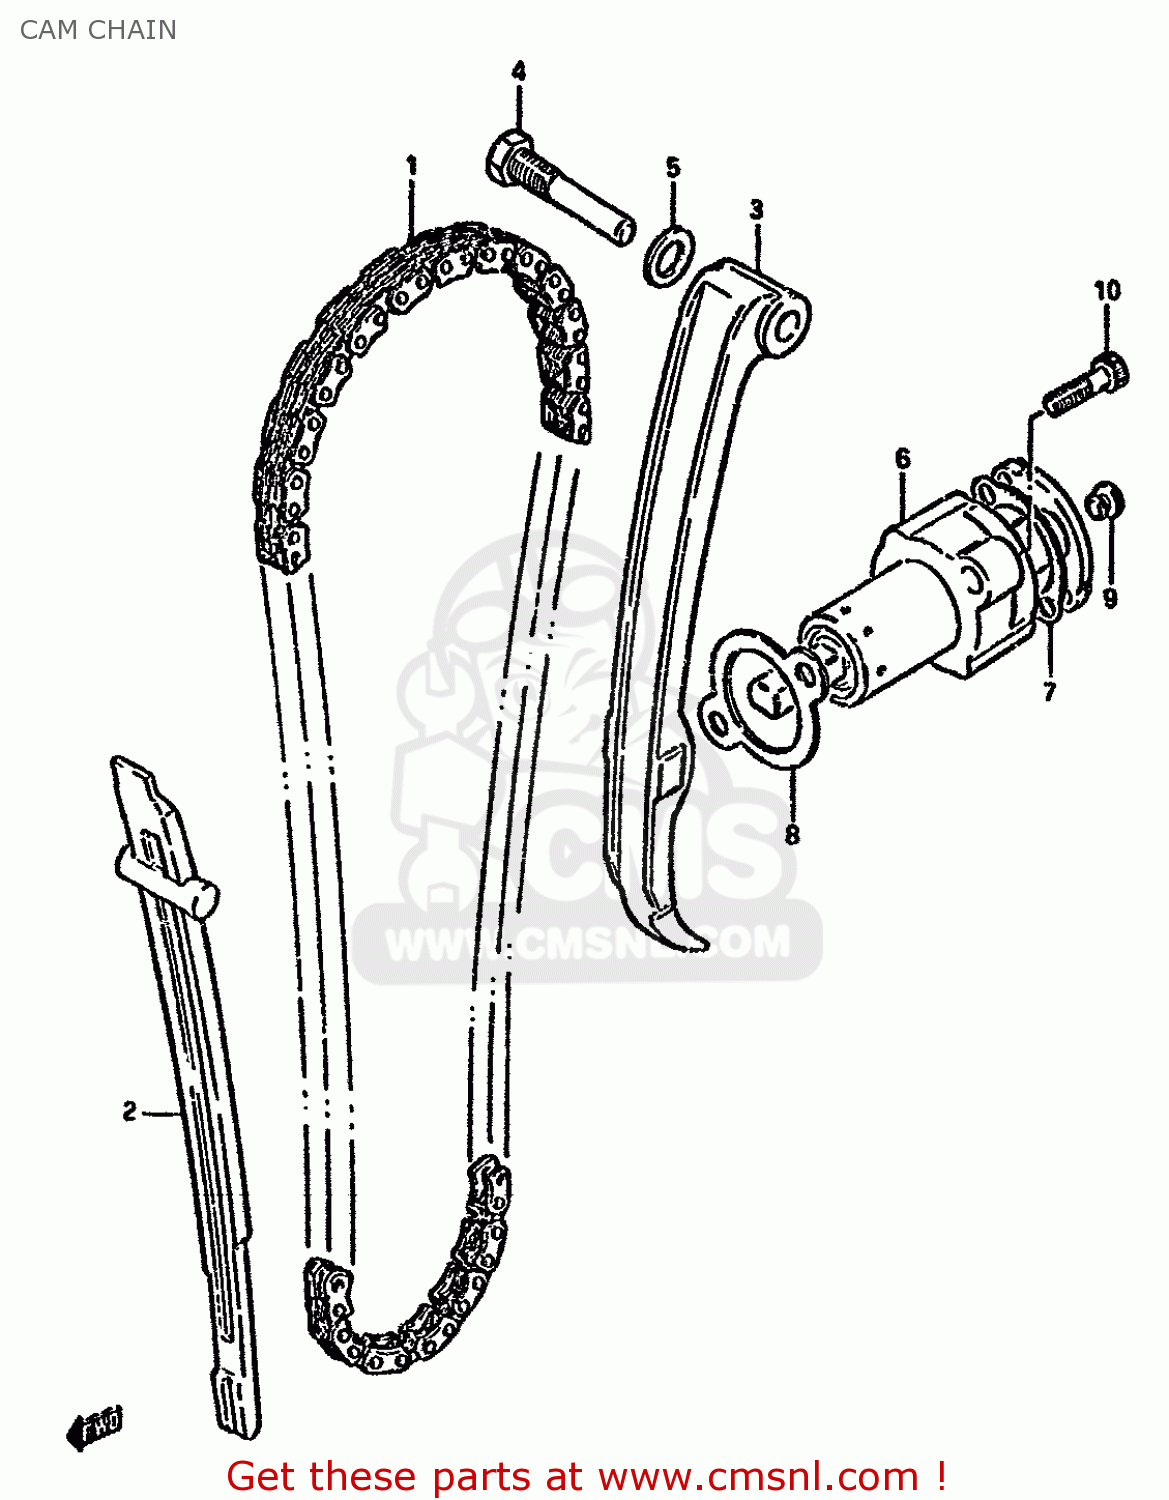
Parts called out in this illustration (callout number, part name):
1	CHAIN,CAMSHAFT DRIVE
2	GUIDE,CAM CHAIN
3	TENSIONER,CAM CHAIN
4	BOLT
5	GASKET 8.2X14X1 (NAS)
6	ADJUSTER ASSY,TENSIONER
7	GASKET,ADJUSTER CAP (NAS)
8	GASKET,TENSIONER ADJUSTER (NAS)
9	PLUG,ADJUSTER
10	BOLT
